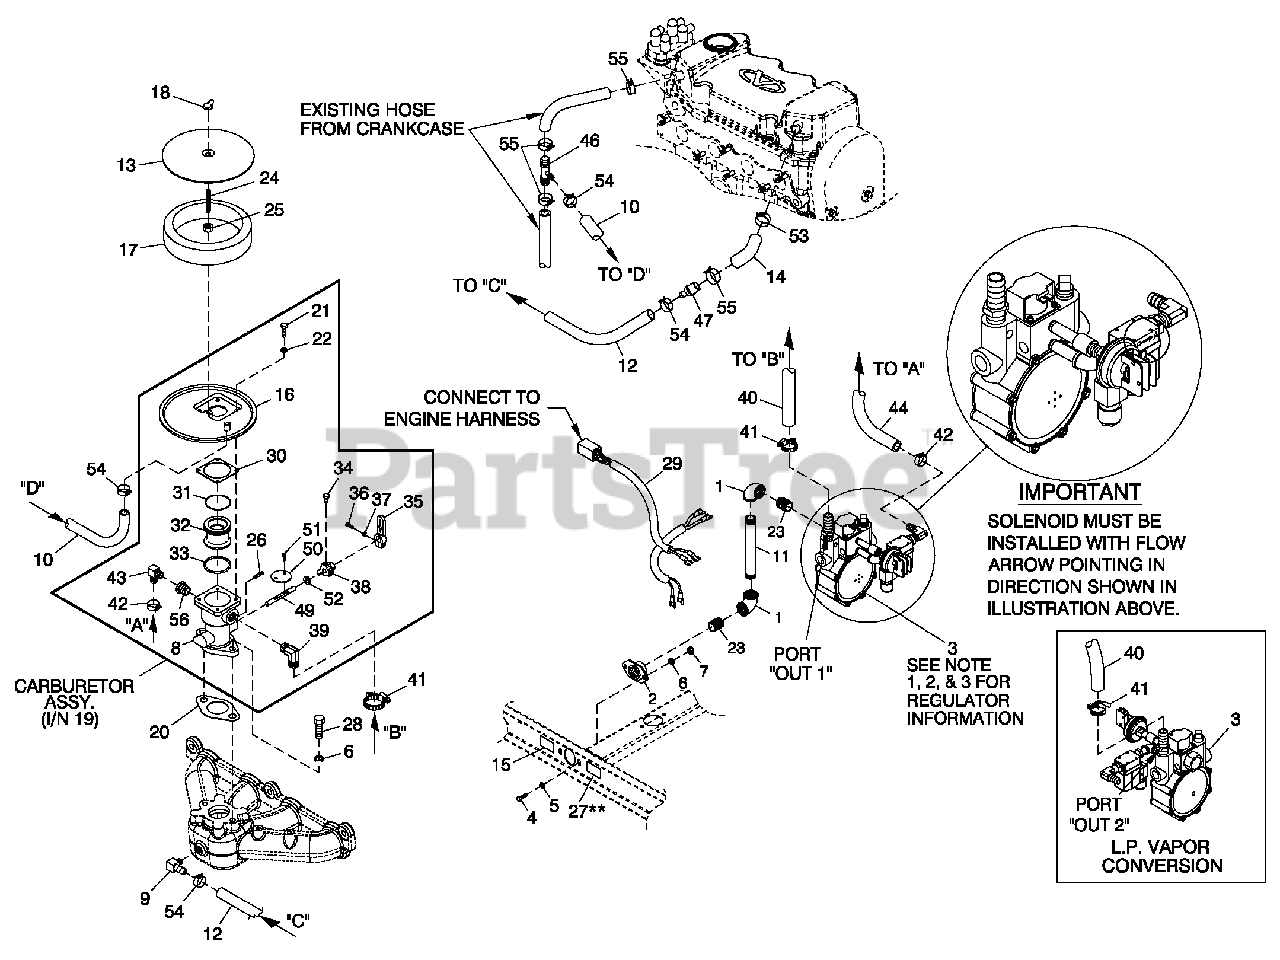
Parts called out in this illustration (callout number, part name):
1	ELBOW 90D 3/4 NPT
2	FLANGE FUEL INLET
3	FUEL REGULATOR 1.6L REWORK
4	SCREW HHC M8-1.25 X 20 G8.8
5	WASHER FLAT 5/16 ZINC
6	WASHER LOCK M8-5/16
7	NUT HEX M8-1.25 G8 YEL CHR
8	BODY CARBURETOR ASSEMBLY
9	BARBED EL 90 1/8 NPT X 3/8
10	HOSE 3/8 ID LOW PRES OIL/WATER (16" LG)
11	NIPPLE PIPE 3/4 NPT X 6
12	HOSE 3/8 ID LOW PRES OIL/WATER (12" LG)
13	COVER AIR CLEANER
14	HOSE BREATHER 1.6L
15	DECAL INLET PRESSURE
16	ADAPTER CARB. TO AIR CLNR
17	FILTER ELEMENT
18	NUT WING 1/4-20 NYLK
19	ASSY CARBURETOR 1.6L
20	CARBURETOR GASKET
21	SCREW PPHM M5-0.8 X 12 ZNC
22	WASHER LOCK M5
23	NIPPLE CLOSE 3/4 X 1.375
24	STUD TH 1/4-20 X 3 G2 ZNC FULL
25	NUT HEX 1/4-20 STEEL
26	PIN SPRING 3/16 X 5/8
27	DECAL FUEL INLET NG
28	SCREW HHC 5/16-18 X 1 G5
29	HARNESS FUEL JUMPER SINGLE REG
30	GASKET AIR CLEANER ADAPTER
31	O-RING 2-028 1.38 X 1.50 X .06
32	VENTURI 20MM
33	O-RING 29.82 X 2.62
34	SCREW THROTTLE PIN STOP
35	THROTTLE ARM REWORK
36	SCREW HHM #10-32 X 5/8
37	WASHER LOCK #10
38	LEVER THROTTLE STOP
39	BARBED EL 90 3/8 NPT X 5/8
40	HOSE 5/8 ID LPG & NG (16" LG)
41	CLAMP HOSE #10 .56 - 1.06
42	CLAMP HOSE BAND .41
43	BARBED EL 90 3/16 X 1/8
44	HOSE 3/16 ID FUEL LINE (22" LG)
46	HOSE BARB REDUCR TEE 3/4"-3/8"
47	PCV VALVE 2.5L FORD
49	SHAFT THROTTLE 1.5L
50	THROTTLE VALVE PLATE 27MM
51	SCREW RHMS 6-32 X 1/4 ZINC
52	SEAL SHAFT COVER
53	CLAMP HOSE BAND .88"
54	CLAMP HOSE BAND .63
55	CLAMP HOSE BAND 1.0"
56	BSHG RDCR HEX 1/4 TO 1/8
